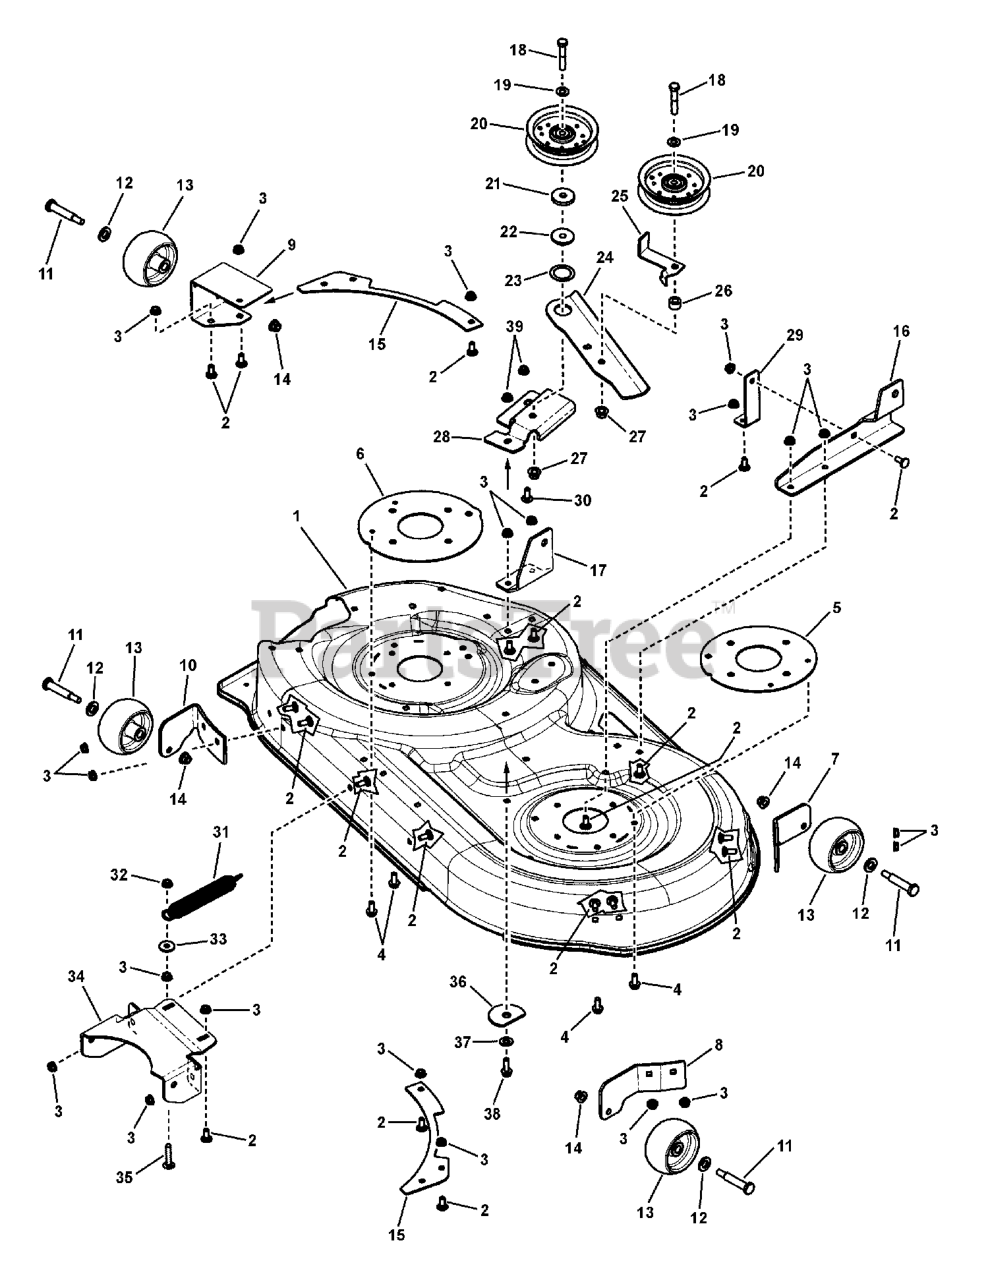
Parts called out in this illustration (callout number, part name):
1	HOUSING, Mower, 42"
2	BOLT, Carriage, Short Neck, 5/16-18 x 3/4, GR 5
3	NUT, Hex Flange Lock, 5/16-18
4	SCREW, Hex Washer Head, Self Tap, 5/16-18 x 1-1/4
5	PLATE, Spindle, LH
6	PLATE, Spindle
7	SUPPORT, Gauge Wheel, LH
8	BRACKET, Gage Wheel, Front, LH
9	BRACKET, Gage Wheel, Rear, RH
10	SUPPORT, Gauge Wheel, RH
11	BOLT, Shoulder, 3/8-16
12	WASHER, Flat, 1/2
13	GAUGE WHEEL
14	NUT, Hex Flange, ESNA, 3/8-16
15	PLATE, Rear
16	BRACKET, Support, Deck, Rear, LH
17	BRACKET, Support, Deck, Rear, RH
18	CAPSCREW, Hex Head, 3/8-16 x 2-1/4, GR 5
19	WASHER, Flat, 3/8
20	PULLEY, Idler
21	WASHER, Flat, 3/8
22	SPACER, 13/32 ID x 1-1/2 OD
23	WASHER, Thrust
24	ARM, Idler
25	BELT GUIDE, Idler
26	SPACER, 3/4 OD x 3/8 ID x 1/2"
27	NUT, Hex Flange Lock, 3/8-16, GR F
28	BRACKET, Idler
29	SUPPORT, Brace
30	BOLT, Carriage, Short Neck, 5/16-18 x 7/8, GR 5
31	SPRING, Extension
32	NUT, Hex Flange, Two Way Lock, 5/16-18
33	WASHER, Flat, .34 ID x 1" OD
34	BRACKET, Hanger, Front
35	BOLT, Carriage, Short Neck, 5/16-18 x 1-3/4, GR 5
36	WASHER, Flat, Special, 1/2 ID x 2-1/2 OD
37	WASHER, Flat, 3/8
38	BOLT, Hex Flange Lock, 5/16-18 x 1, GR 5
39	NUT, Hex Flange Lock, Large, 5/16-18
